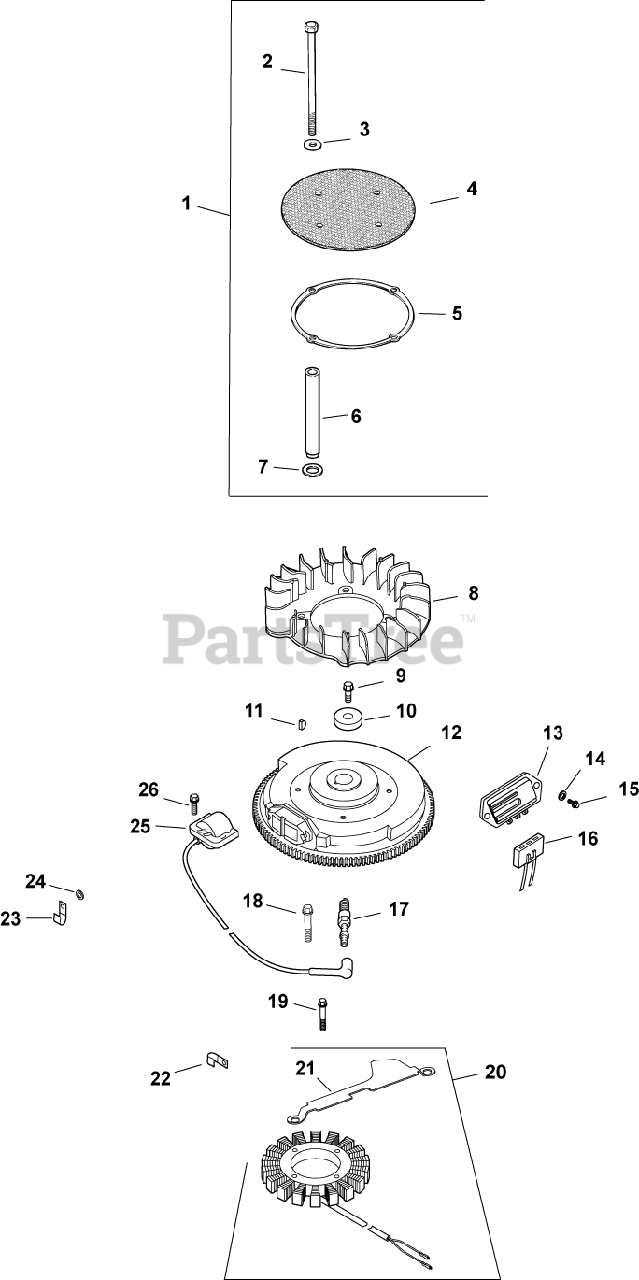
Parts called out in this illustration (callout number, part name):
1	KIT, CHOPPER SCREEN
2	SCREW, CAP M6X1.0X99.5
3	WASHER, FLAT 1/4" (O.D. 5/8")
4	SCREEN, GRASS-USE 24 162 41-S
5	RING, SUPPORT USE 25 141 08-S
7	WASHER, SPRING 10 MM
8	FAN (DOMED)-USE 24 157 17-S
9	SCREW, FLG M10X1.5X45 - (#25086361S)
10	WASHER, FLAT 13/32"
11	KEY, 3/16" X 5/8"
12	FLYWHEEL, PAINTED-USE 24 025 55-S
13	REG/RECT-15 AMP (KM)-USE 41 403 10-S
14	WASHER, FLAT 3/16"
15	SCREW, PHL HD #11-16X7/8"
16	CONNECTOR, BODY (KM)-USE 25 155 41-S
17	PLUG, SPARK (STD)
18	SCREW, M5X0.8X25 - (#25086402S)
19	SCREW, SKT SET #10-24X1/4"
20	KIT, 15 / 20 AMP STATOR
21	BRACKET, STATOR WIRE
22	CLIP, TUBE & WIRING (KM)
23	CLIP, CABLE
24	WASHER, FLAT 1/4" (O.D. 1/2")
25	MODULE, IGNITION-USE 24 584 45-S
26	SCREW, FLG THD FRM M5X.8X20-(#25086399S)
